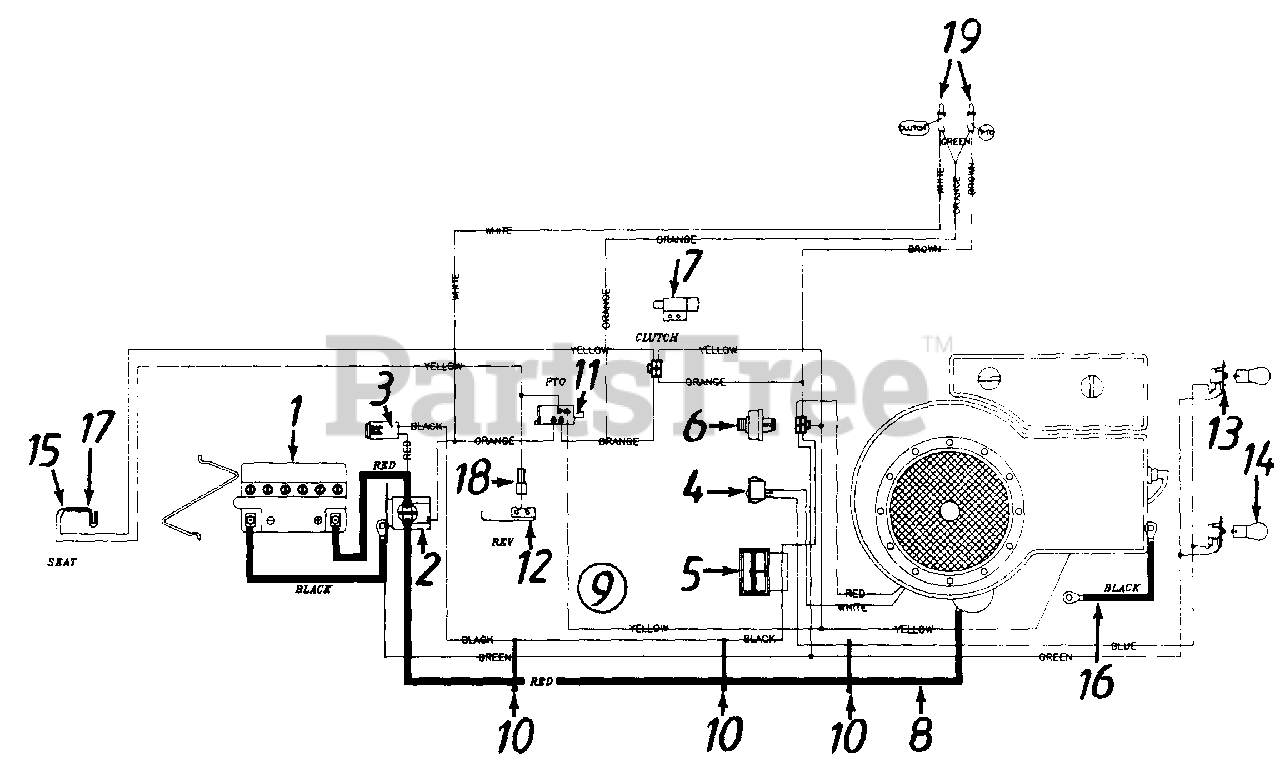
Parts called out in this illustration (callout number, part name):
1	Battery
2	Soleniod
3	Fuse 7.5 Amps
4	Light Switch
5	Ammeter
6	Ignition Switch
7	Safety Switch (Clutch)
8	Electric Wire 30" Lg.
9	Wire Harness w/Ammeter
11	Safety Switch (Deck)
12	Safety Switch (Reverse)
13	Socket
14	Bulb (Headlight)
15	Safety Switch (Seat)
16	Ground Wire 7.5" Lg.
17	Safety Switch (Seat)
18	Ext. Wire
19	Bulb (Monitor)
